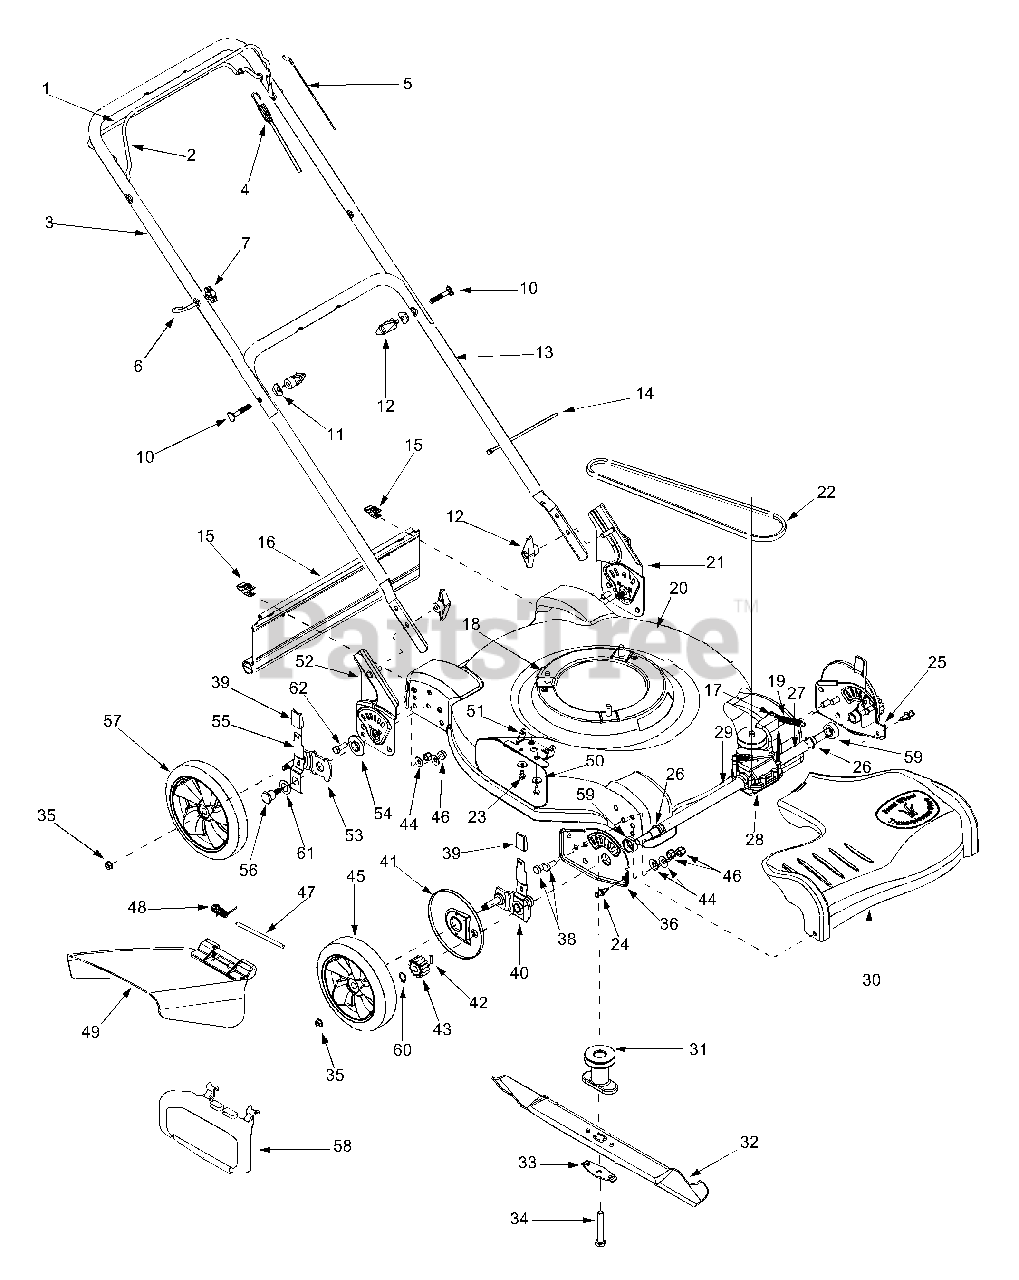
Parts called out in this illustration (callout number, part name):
1	Drive Control Handle
4	Drive Control Cable
5	Blade Control Cable - 37.75"
6	Eye Bolt
7	Wing Nut 1/4-20
10	Carriage Bolt 5/16-18 x 2.0
11	Shoulder Washer.320 ID x.93 OD
12	Wing Nut 5/16-18
14	Cable Tie
15	Hinge Clip
16	Trail Shield
17	Screw
18	Hex Washer Screw 3/8-16 x 1.0
19	Spring.47 OD x 2.50
22	V-Belt
23	Hex Washer Screw 1/4-20 x.500
24	Rivet
26	Retainer Ring
27	Sleeve Spacer.550 ID X 3.30
28	Transmission Assembly Complete
29	Sleeve Spacer.550 ID x7.95
30	Transmission Cover
31	Blade Adapter, One Piece
32	Mulching Blade 22"
33	Bell Blade Support
34	Hex Cap Screw 3/8-24 x 1.5
35	Lock Nut 3/8-16
38	Hex Cap Screw 3/8-16 x 1.00
39	Adjustment Knob
40	Spring Lever Assembly - RH (FWD)
41	Wheel Dust Cover
42	Pin
43	Spur Gear 14T - RH
44	Bell Washer .401 ID x.870 OD
45	Front Wheel Assembly 8 x 1.8
46	Hex Lock Nut 3/8-16
47	Hinge Pin
48	Torsion Spring
49	Side Discharge Assembly
50	Bell Washer.265 ID x.75 OD
51	Deflector Chute Adapter
54	Height Adjustment Bearing
55	Spring Lever
56	Shoulder Screw 3/8-16
57	Rear Wheel 8 x 1.8
58	Snap Mulching Plug
59	Bearing Spacer
60	Snap Ring.500
61	Bell Washer.760 ID x 1.25 OD
62	Hex Cap Screw 3/8-16 x 1.0
